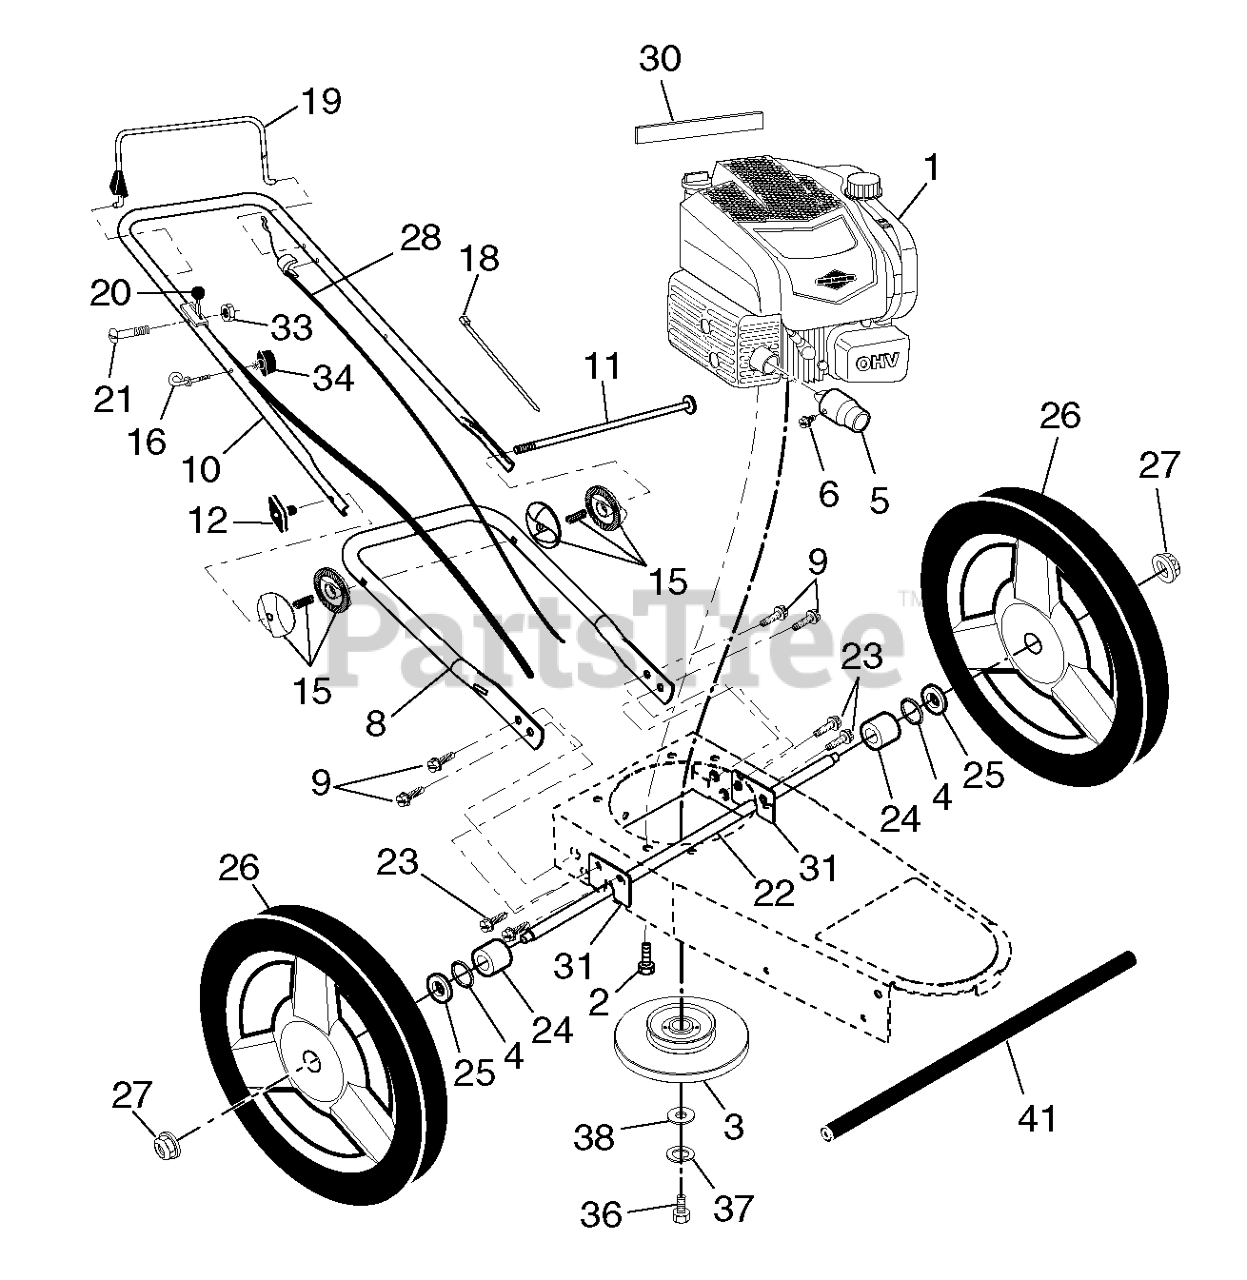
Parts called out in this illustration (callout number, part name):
2	BOLT 3/8-16X1-1/8
3	PULLEY/FLYWHEEL.TRIMMER.25MM
4	O-RING..070X.487.NEOPRENE
5	SPARK.ARRESTOR.W26
6	SCREW #8 X 1/4- SHEET METAL SP
8	HANDLE.LOWER.STRING.TRIMMER.GR
9	BOLT.HEX.HD.WASHER.5/16-18X.75
10	HANDLE.UP.STRING.TRIMMER.GREY
11	BOLT.HANDLE.WHEELED.TRIMMER
12	KNOB, DEFLECTOR
15	ADJSTR.ASSEM.HANDLE.WHLD.TRIMM
16	GUIDE.ROPE.BLK.ZINC.CHROM
18	TIE GUIDE
19	BAIL.ARM.ASM.TRIMMER.668
20	CONTROL.ENGINE.STOP.BRAKE
22	AXLE.TRIMMER
23	BOLT.HEX.HD.WASHER.5/16-18X.75
24	SPACER.AXLE.STRING.TRIMMER
25	WASHER.FLAT.1/2
26	WHEEL.12X1.75.CF H3SPK.RAD3.BB
27	NUT.HEX.FLANGE.3/8-16.LOCKNUT
28	CABLE.DRIVE.TRIMMER
30	DECAL.TRIMMER.CHASSIS.SYM
31	BRACKET, AXLE
33	NUT.HEX.FLANGE.1/4
34	T-KNOB.NEW ROPE GUIDE
36	SCREW, HEX HD 3/8-24 X 1-3/8
37	LOCKWASHER
38	WASHER,HARDEN
41	TUBE.AXLE.TRIMMER.BLACK
